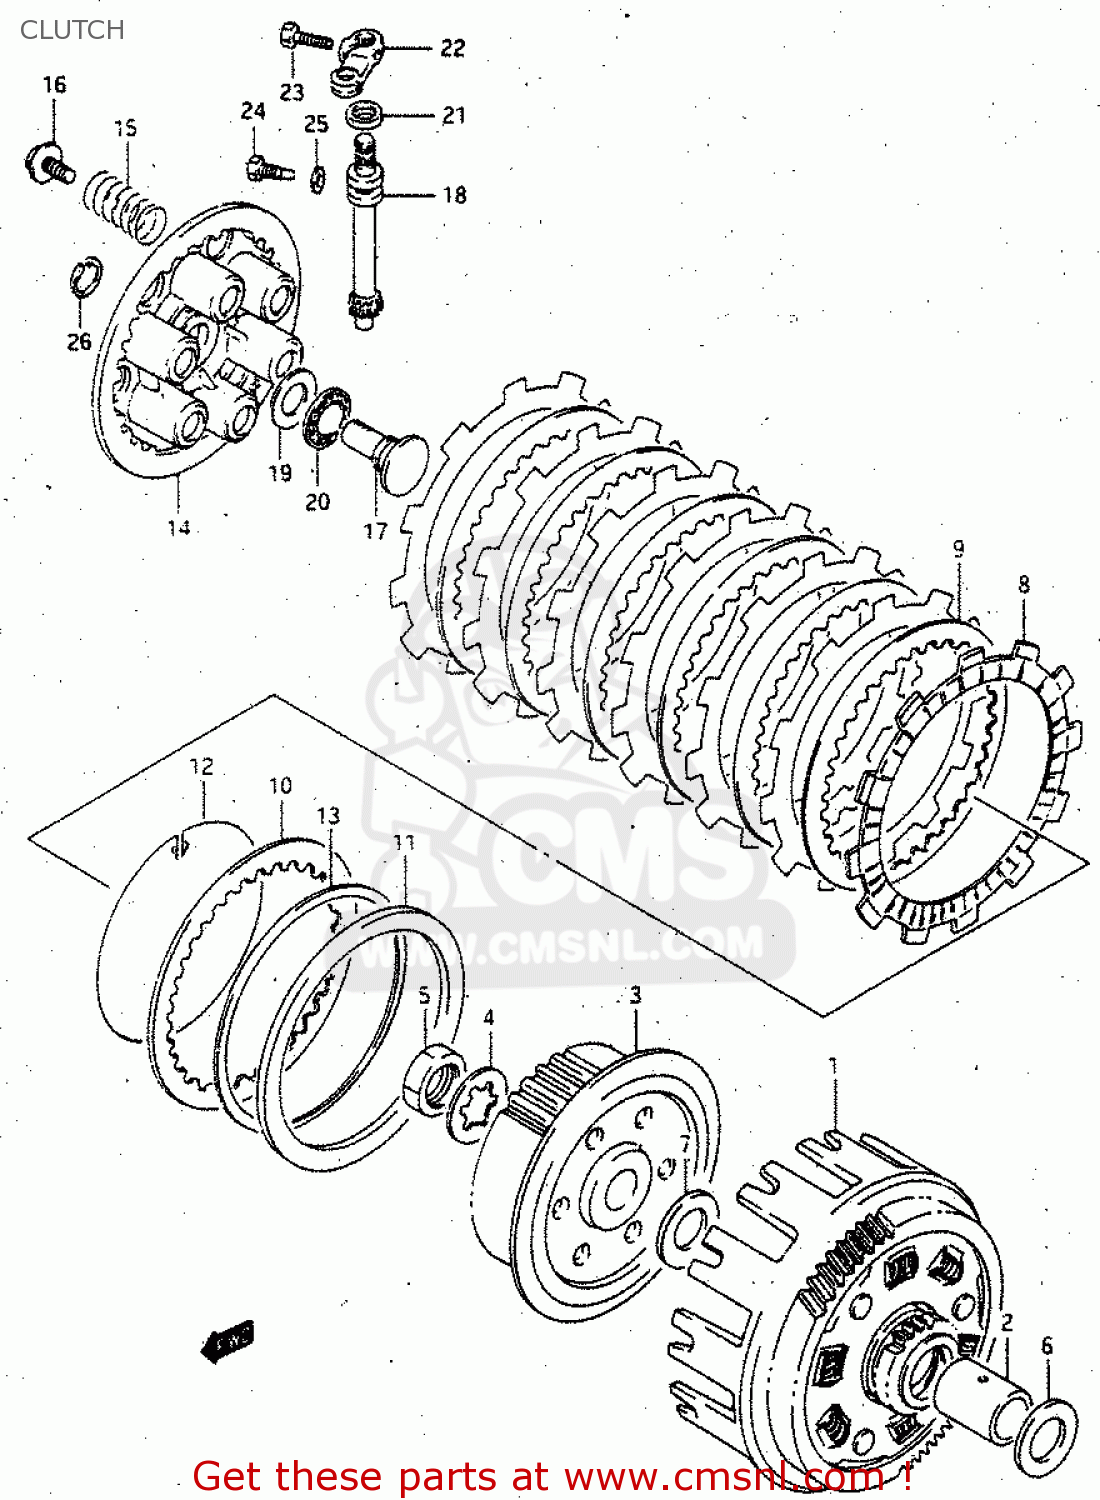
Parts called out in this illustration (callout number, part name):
1	GEAR ASSY,PRIM
2	SPACER,PRIMARY DRIVEN
3	HUB,CLUTCH SLE
4	WASHER,LOCK
5	NUT
6	WASHER(20X36X3)
7	WASHER(20X36X2)
8	PLATE,CLUTCH DRIVE (NAS)
9	PLATE,CLUTCH DRIVEN (NAS)
10	PLATE,CLUTCH DRIVEN(T:2.0) (NAS)
11	SEAT,WAVE WASHER
12	RING,STOPPER
13	WASHER
14	DISC,CLUTCH PRESSURE
15	SPRING
16	BOLT
17	RACK,CLUTCH RELEASE
18	PINION,CLUTCH RELEASE
19	WASHER
20	BEARING(15X28X2)
21	SEAL,OIL(10X17X5)
22	ARM,CLUTCH RELEASE
23	BOLT
24	BOLT(6X12)
25	WASHER
26	RING,SNAP
